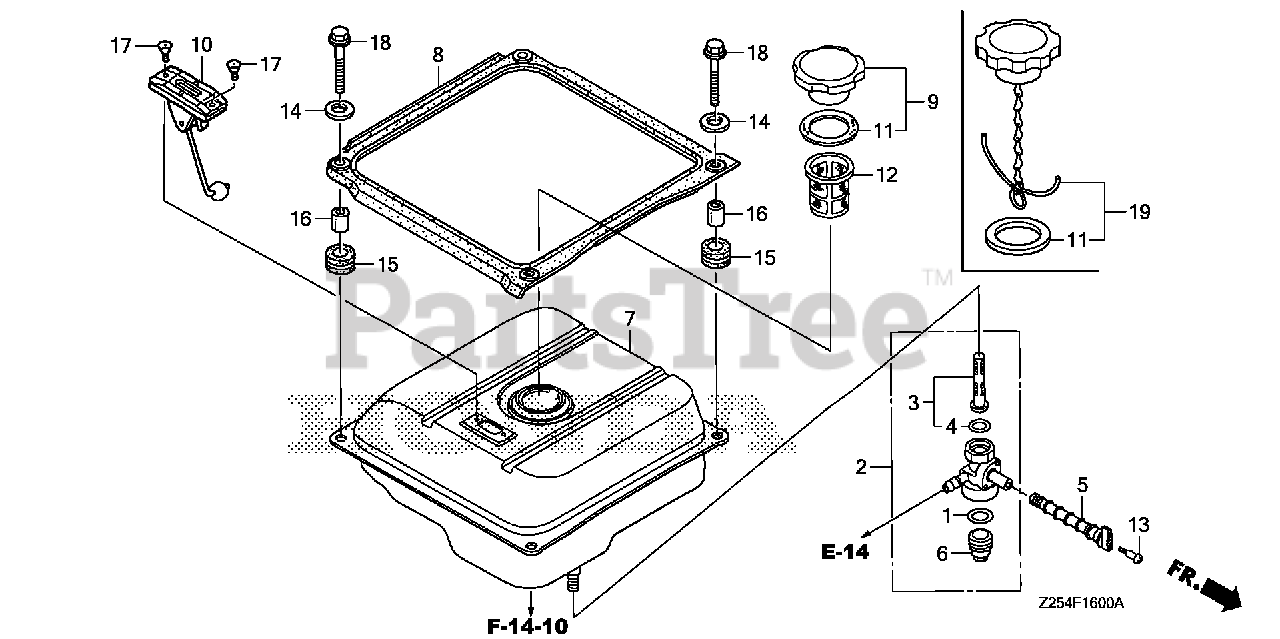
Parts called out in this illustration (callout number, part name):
1	GASKET, FUEL STRAINER CUP
2	PETCOCK ASSY.
3	SCREEN SET, FUEL STRAINER
4	O-RING (9.0X1.3)
5	LEVER, PETCOCK
6	CUP, FUEL STRAINER
7	TANK, FUEL *R280* (POWER RED)
8	SEAL, FUEL TANK
9	CAP, FUEL FILLER
10	METER ASSY., FUEL
11	GASKET, FUEL FILLER CAP
12	FILTER, FUEL
13	SCREW, PAN (4X19)
14	WASHER (6MM)
15	CUSHION, TANK RUBBER
16	COLLAR, TANK CUSHION
17	SCREW, FLAT (5X10)
18	BOLT, FLANGE (6X25)
